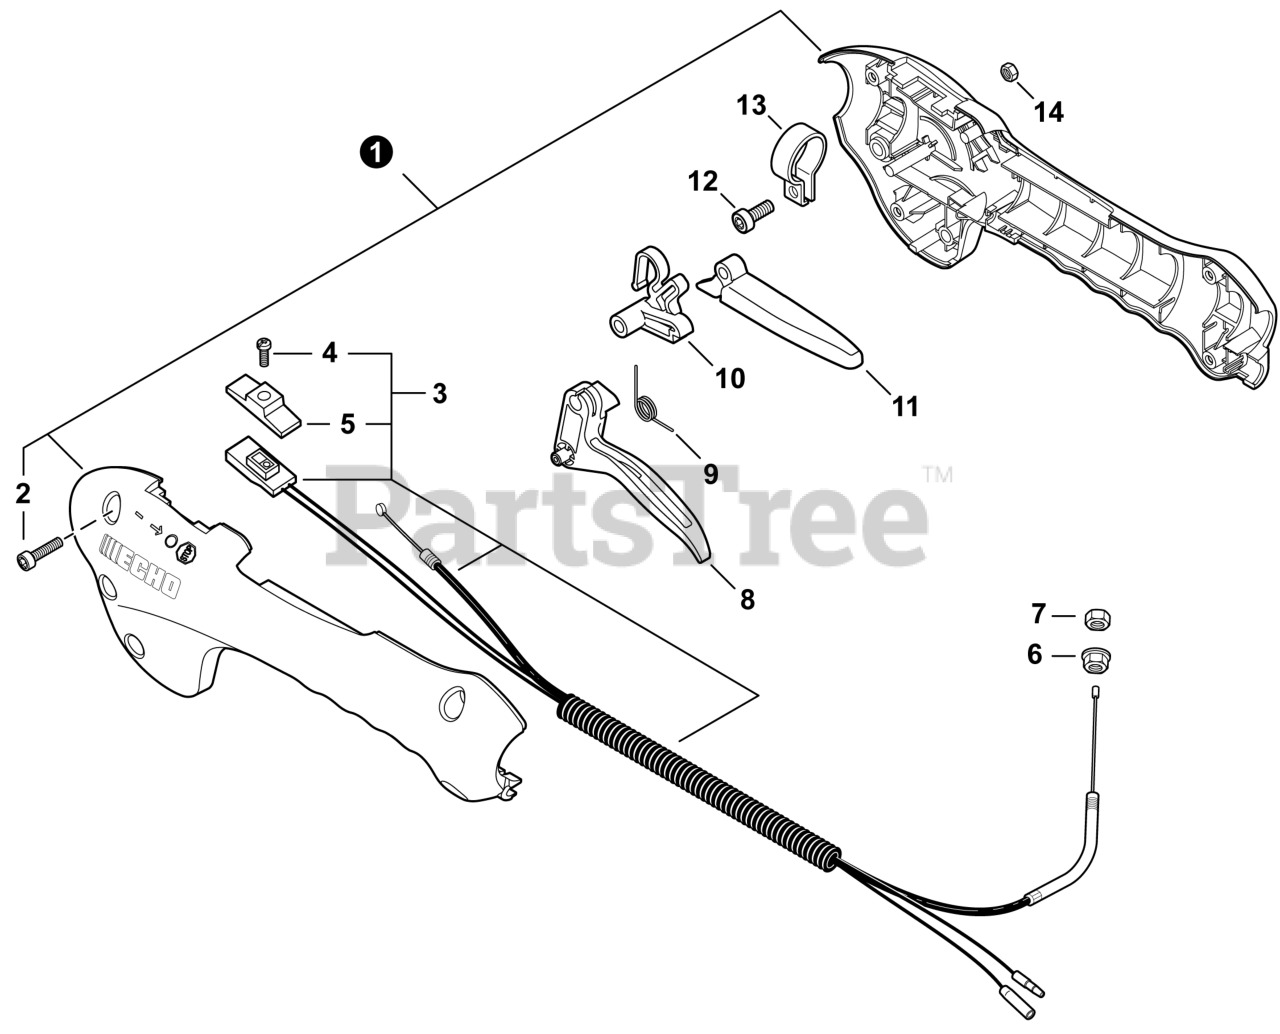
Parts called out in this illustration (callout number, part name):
1	CONTROL HANDLE SET
2	BOLT, TORX 4x16
3	CABLE ASSY, CONTROL
4	SCREW 3x10
5	KNOB, SWITCH - ORANGE
6	NUT, FLANGE M6
8	TRIGGER, THROTTLE
9	SPRING, TRIGGER
10	LOCKOUT, THROTTLE
11	LEVER, THROTTLE LOCKOUT
12	BOLT, TORX 5x16
